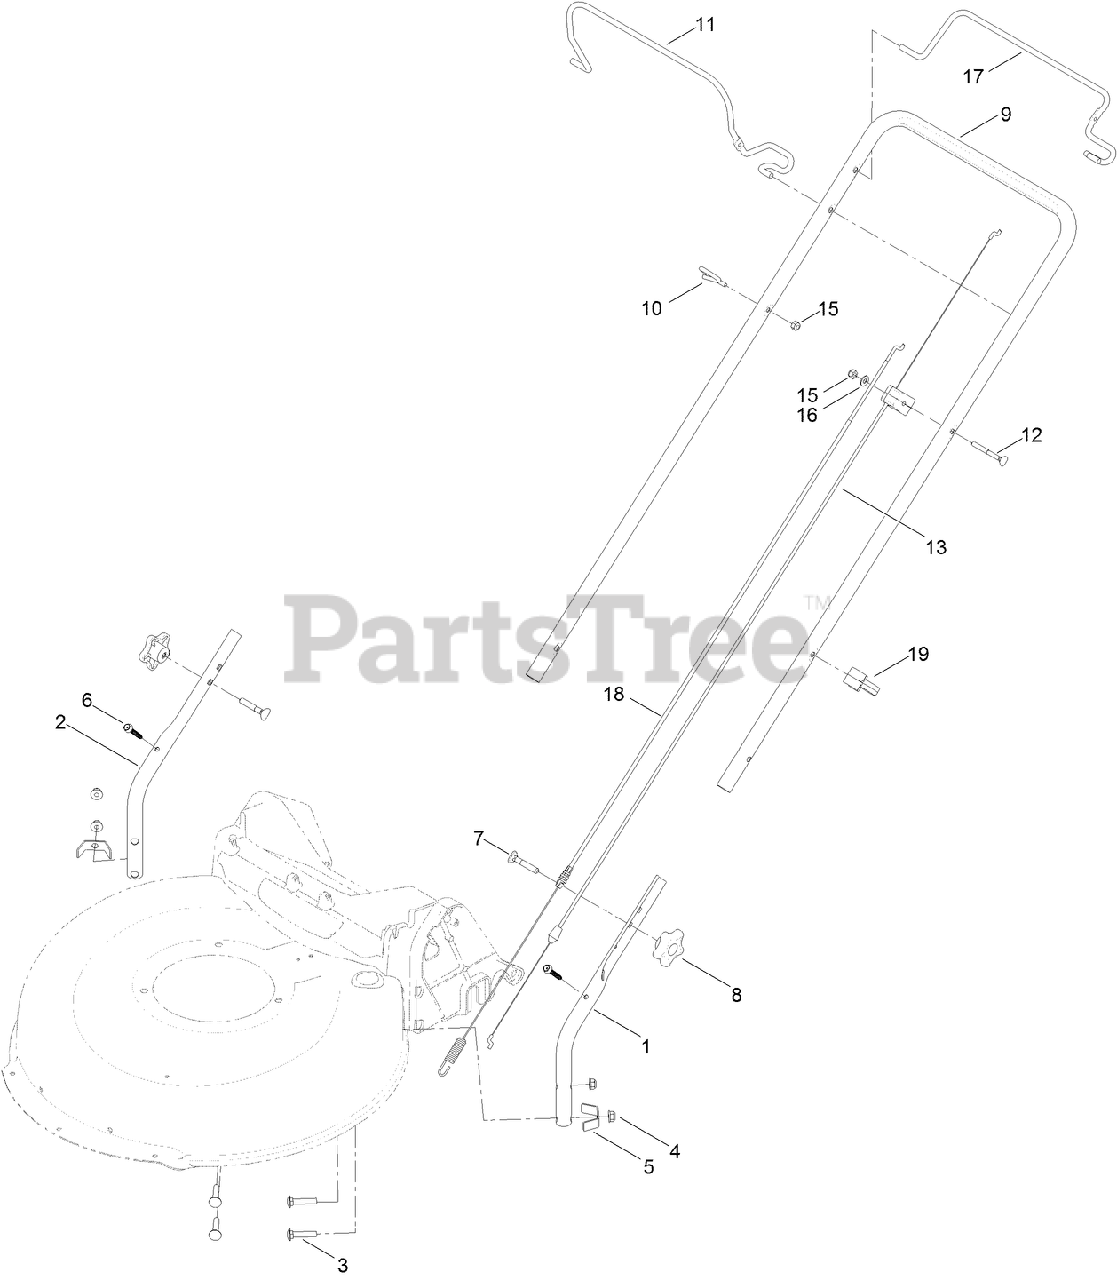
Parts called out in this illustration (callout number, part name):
3	BOLT-CARR
4	NUT-FLANGE, NI
5	BRACKET-CHUTE
6	SCREW-FLANGE, SERRATED
7	SCREW-HANDLE
8	KNOB-HANDLE
9	HANDLE-UPPER
10	GUIDE-ROPE
12	SCREW-HANDLE
13	CABLE-BRAKE
15	NUT-LOCK, NI
16	WASHER-FLAT
17	BAIL-TRACTION
18	CABLE-TRACTION
19	GUIDE-CABLE
